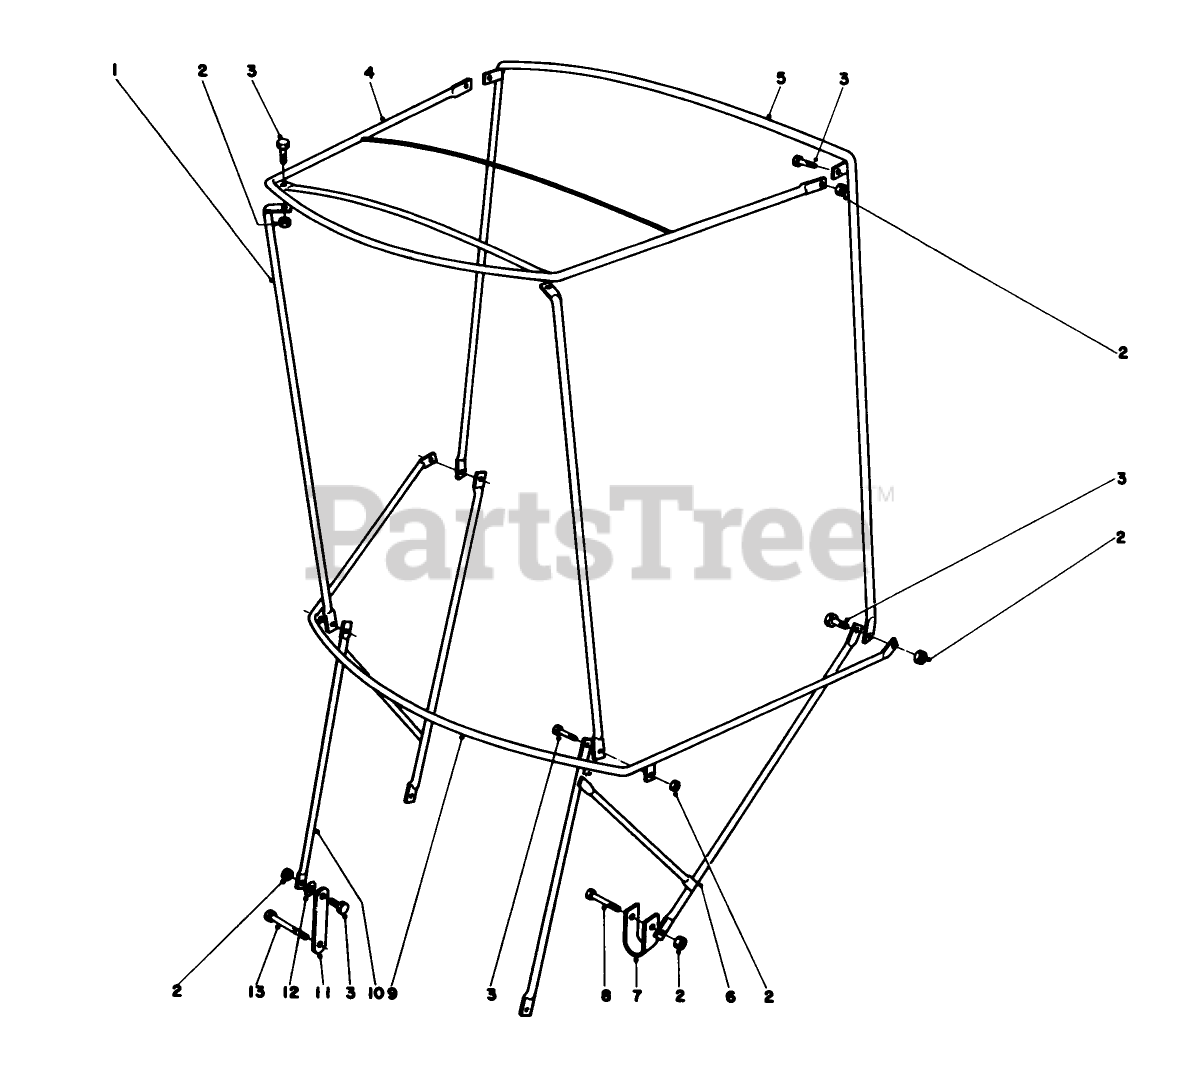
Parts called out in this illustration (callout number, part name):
3	Bolt
8	SCREW-HH
12	WASHER-LOCK/EXT
13	SCREW-HH
